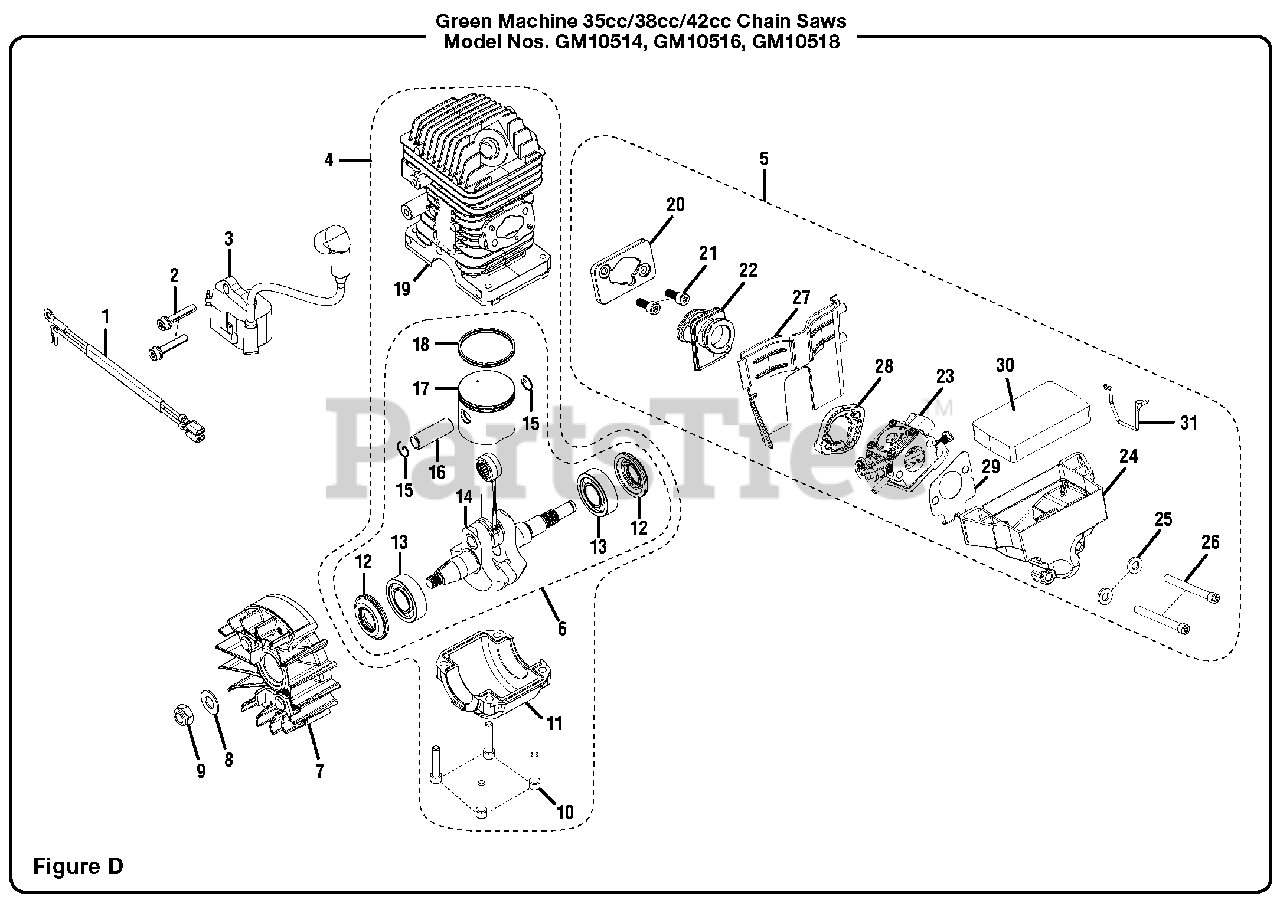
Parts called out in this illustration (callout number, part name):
1	Ignition Switch Harness
2	Bolt (M5 x 25.4 mm)
3	Ignition Module
4	Short Block Assembly (Inc. Key Nos. 10-19)
5	Intake Assembly (Inc. Key Nos. 20-31)
6	Crankshaft & Piston Assembly (Inc. Key Nos. 12-18)
7	Flywheel Assembly
8	Washer
9	Flywheel Nut
10	Screw (M5 x 24 mm)
11	Crankshaft Case
12	Crankshaft Seal
13	Ball Bearing
14	Crankshaft & Rod Assembly
15	Spring Retainer
16	Piston Pin
18	Piston Ring
20	Press Plate, Cylinder
21	Bolt (M5 x 14 mm)
22	Intake Boot
23	Carburetor
24	Air Filter Box
26	Bolt (M5 x 50 mm)
28	Press Plate, Carb
29	Carb Bracket
30	Air Filter
31	Throttle Rod
